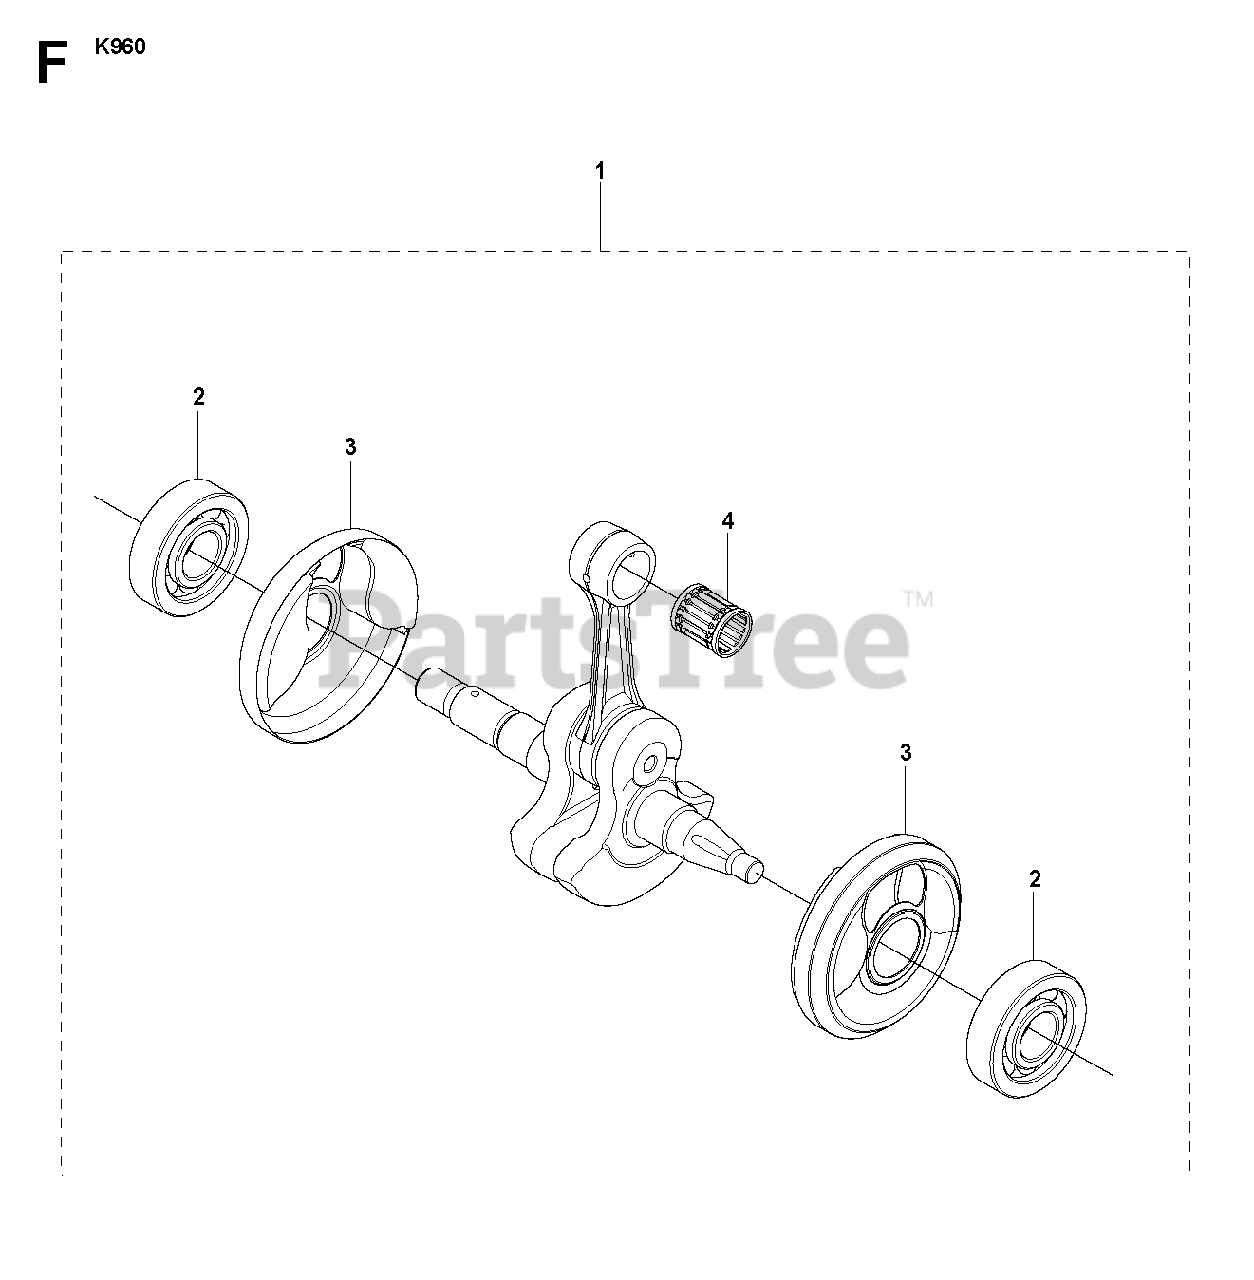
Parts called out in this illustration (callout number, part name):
1	CRANKSHAFT ASSYIncl. 2 - 4
2	BALL BEARING
4	NEEDLE BEARING
